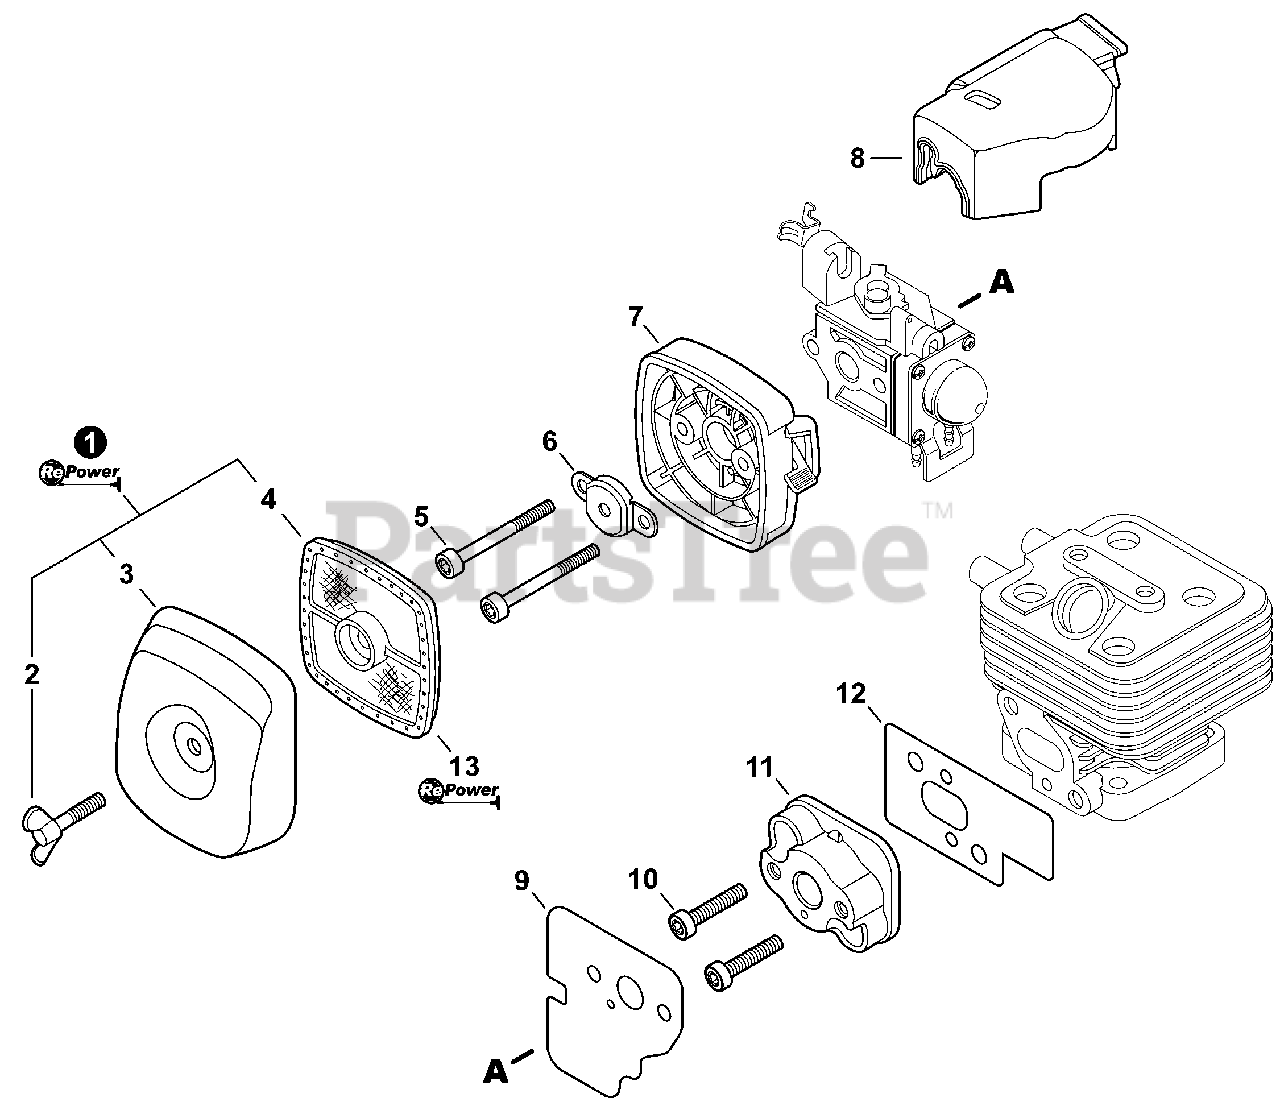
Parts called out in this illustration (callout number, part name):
1	FILTER KIT, AIR
2	BOLT, WING 5×20
3	COVER, AIR FILTER - BLACK
4	FILTER, AIR - DOUBLE LAYER
5	BOLT, TORX 5×65
6	PLATE, PREVENT
7	CASE, AIR FILTER - BLACK
8	COVER, DUST
9	GASKET, INTAKE
10	BOLT, TORX 5×25
11	INSULATOR, INTAKE
12	GASKET, INTAKE
13	TUNE-UP KIT - REPOWER
